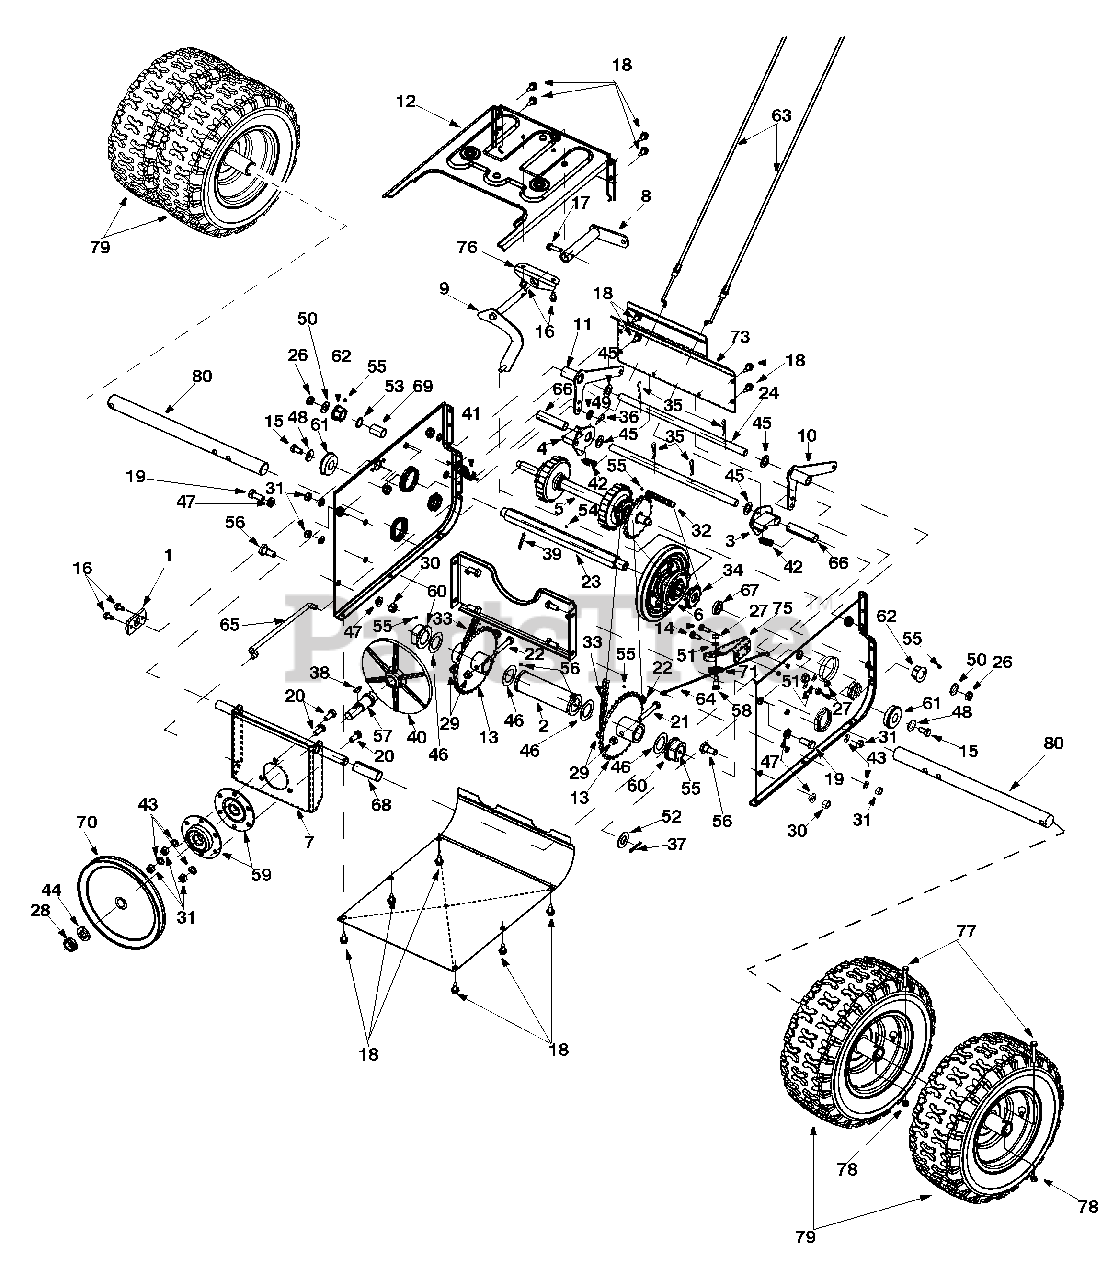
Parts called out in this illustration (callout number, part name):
1	Support Bracket: Pivot
2	Bush Assembly
3	Dogg Assembly LH
4	Dogg Assembly RH
5	Shift Assembly
6	Wheel Bearing Assembly
10	Auger Actuator Bracket Assy.
13	Sprocket Assembly
14	Hex Screw 1/4-28 x .625"
15	Hex Screw 5/16-18 x .625"
16	TT Screw 1/4-20 x .5"
17	TT Screw 1/4-20 x 1"
18	TT Screw 1/4-20 x .625"
19	Hex Screw 3/8-16 x .880"
20	Hex Screw 5/16-18 x .75"
21	Hex Screw 5/16-18 x 2"
22	Hex Screw 5/16-18 x 1.75"
23	Hex Shaft: Drive
24	Actuator Shaft
27	Hex Nut 1/4-28
28	Jam Lock Nut
29	Hex Lock Nut
30	Hex Nut 3/8-16
31	Hex Nut 5/16-18
35	Hairpin Clip
36	Hairpin Clip
37	Cotter Pin
38	Key
39	Roll Pin
40	Drive Plate
41	Extension Spring
42	Extension Spring
43	Lock Washer 5/16
44	Lock Washer 5/8
45	Flat Washer
46	Flat Washer
47	Lock Washer
48	Beleville Washer
49	Flat Washer
50	Flat Washer
51	Lock Washer
52	Flat Washer
53	Flat Washer
54	Lubricant
56	Shoulder Screw
57	Spindle: Drive Plate
58	Shoulder Screw 1/4-28 x .375"
59	Bearing Housing Assembly
60	Flange Bearing
61	Ball Bearing
62	Hex Flange Bearing
63	Steer Cable
64	Idler Cable: Auger
65	Clutch Rod: Drive
66	Split Spacer
67	Spacer
68	Split Spacer
70	Drive Pulley
71	Roller Cable
77	Hex Screw 5/16-18 x 2"
80	Axle: Wheel
